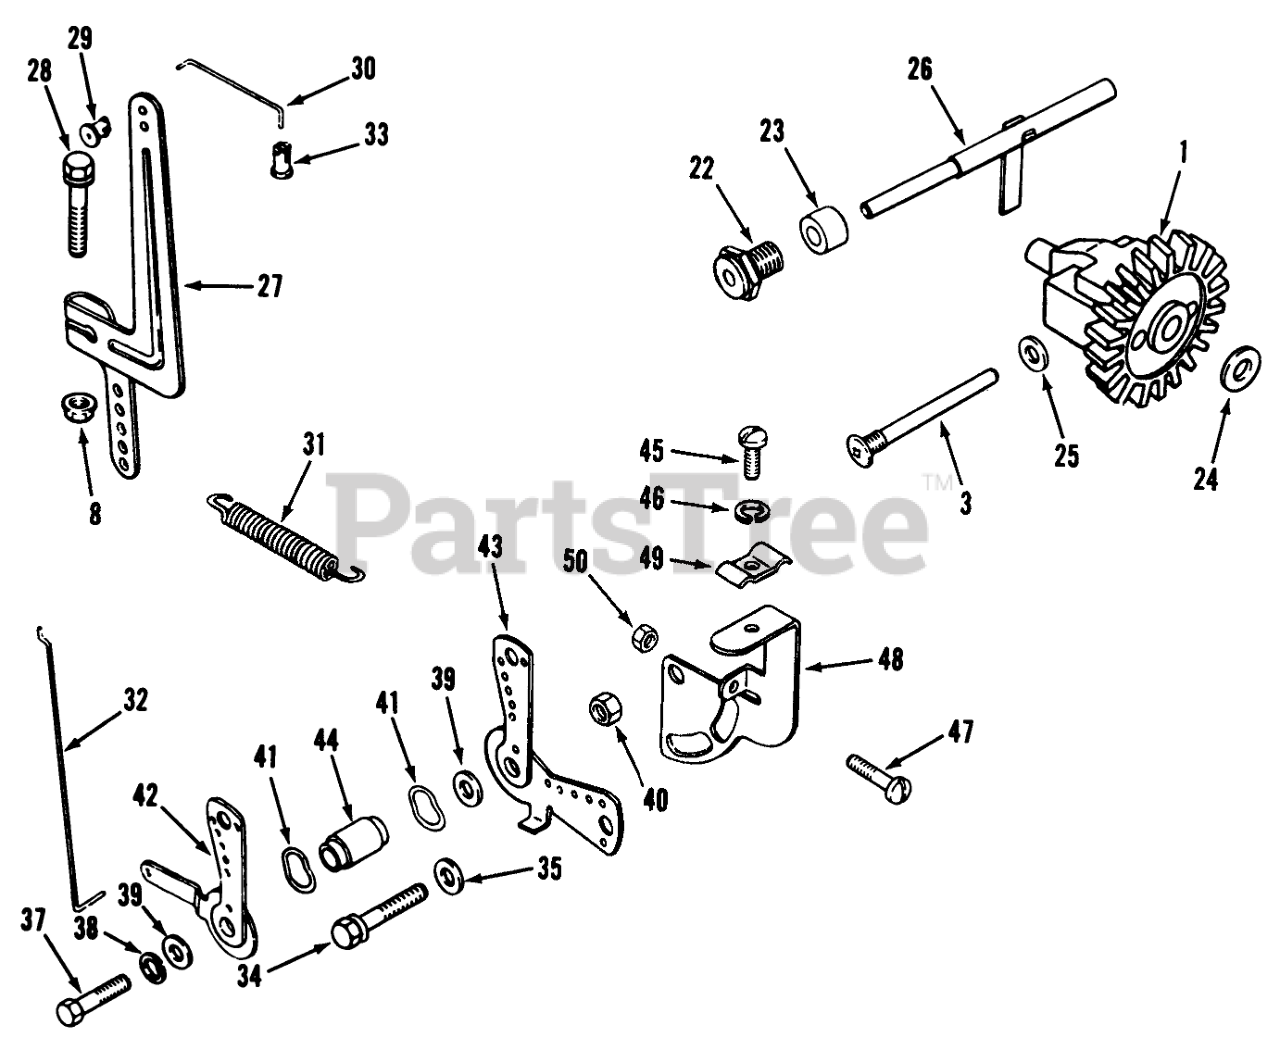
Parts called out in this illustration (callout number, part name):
1	KOHLER A-235743-5
3	KOHLER 231355
8	KOHLER X-799-1
22	KOHLER 235476
23	KOHLER X-400-80
24	KOHLER 237022
25	KOHLER 47-099-04
26	KOHLER A-235256-5
27	KOHLER 47-090-20
28	KOHLER X-776-1
29	KOHLER 47-158-07
30	KOHLER 47-079-05
31	KOHLER 47-091-01
32	KOHLER 47-079-01
33	KOHLER 25-158-09
34	KOHLER X-132-6
35	KOHLER X-25-72
37	KOHLER X-5-26
38	KOHLER X-20-1
39	KOHLER X-159-2
40	KOHLER X-76-2
41	KOHLER 275690
42	KOHLER 47-090-07
43	KOHLER 47-090-08
44	KOHLER 47-112-02
45	KOHLER X-67-51
46	KOHLER 25-468-04
47	KOHLER 232556
48	KOHLER 47-126-09
49	KOHLER 47-237-02
50	KOHLER X-72-4
